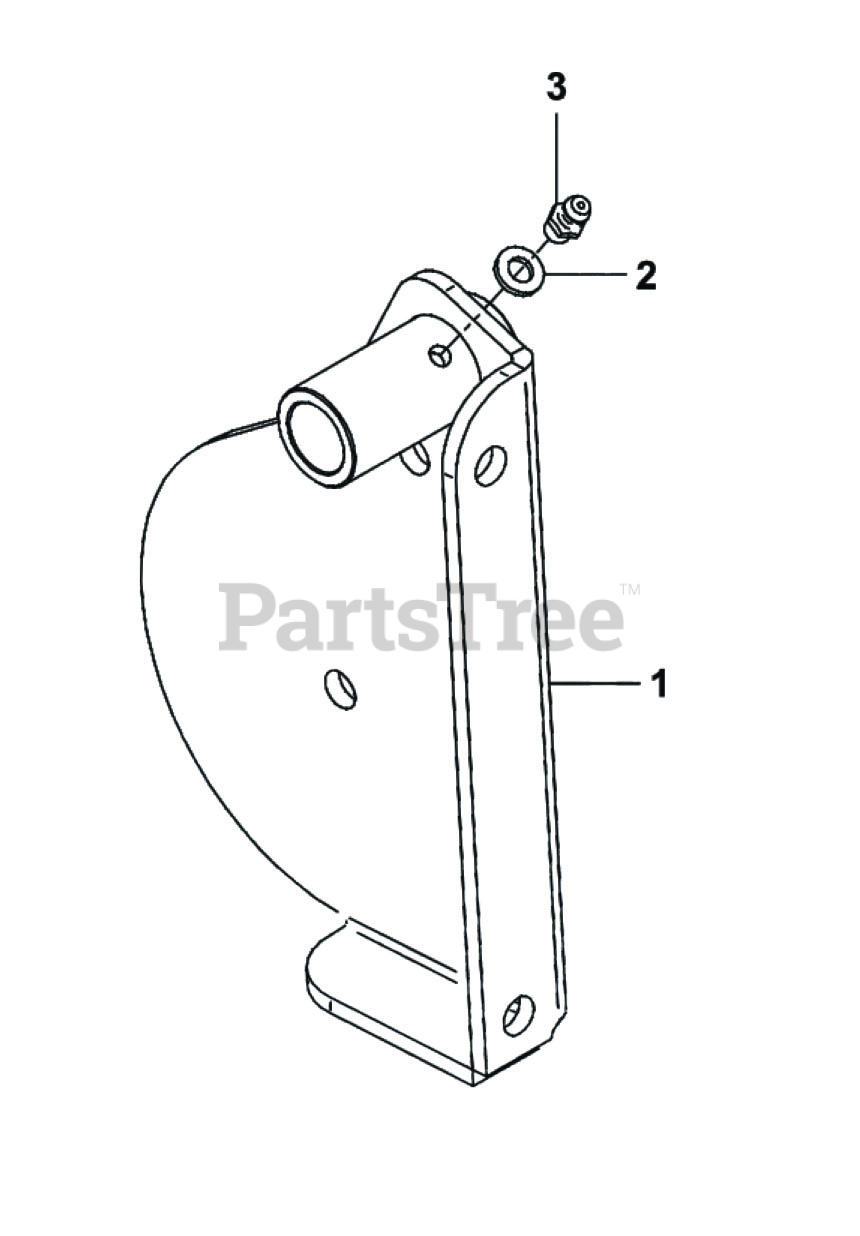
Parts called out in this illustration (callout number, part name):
1	IDLER ARM WELDMENT
2	FLAT WASHER M6 x 12
3	GREASE FITTING
